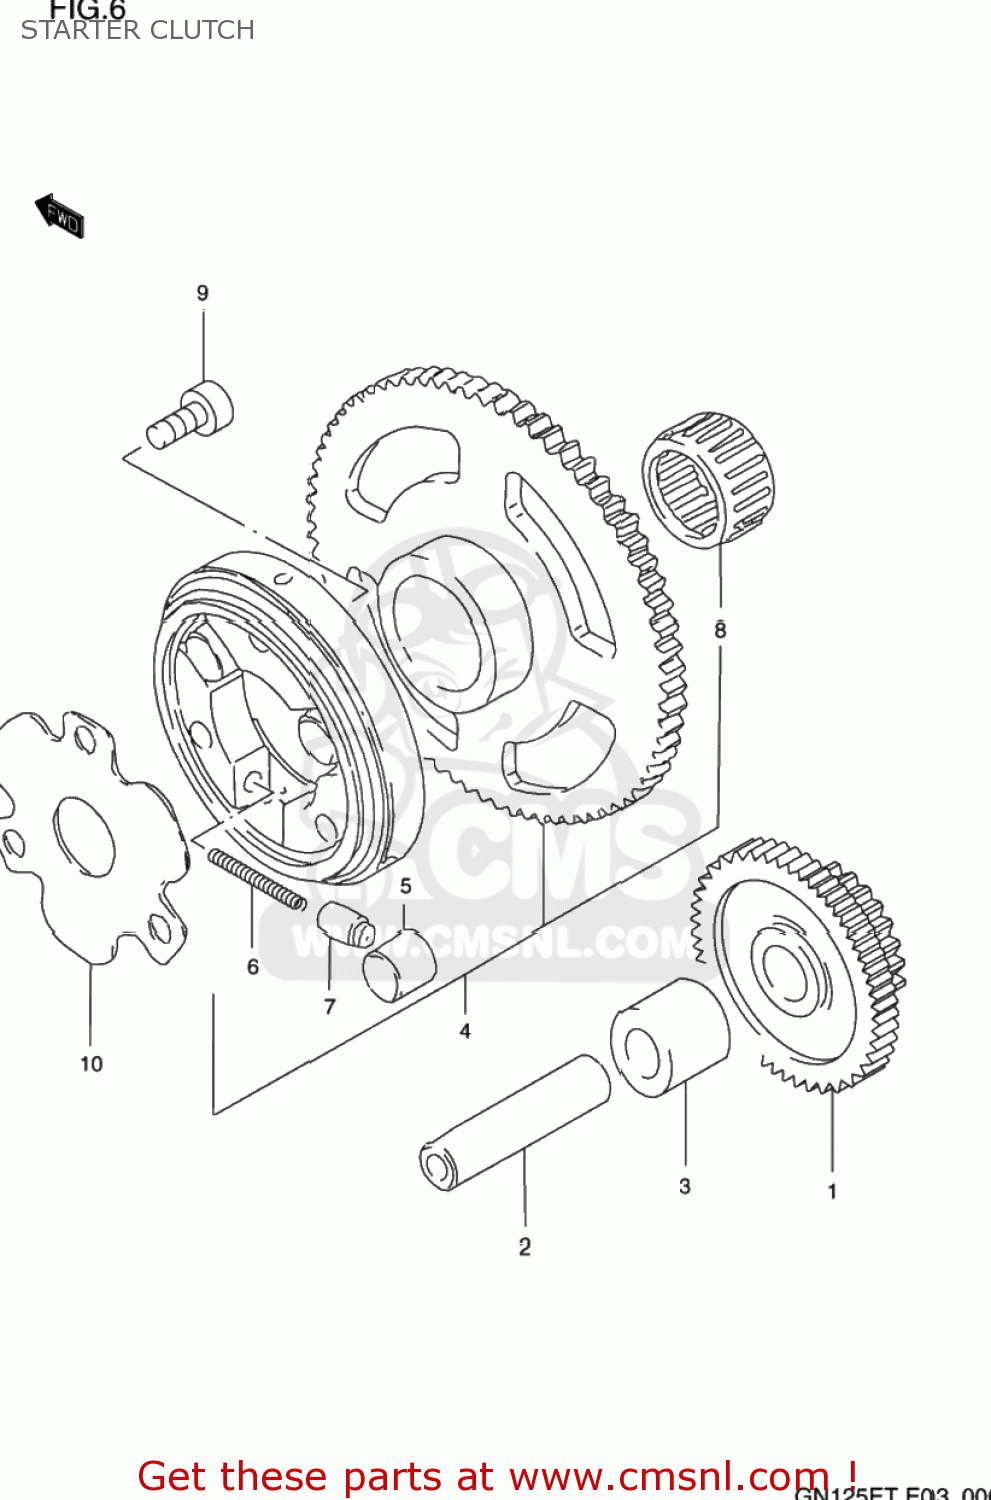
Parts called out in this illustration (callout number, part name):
1	GEAR,STARTER IDLER
2	PIN(7.4X13X56)
3	SPACER(13X19X19)
4	CLUTCH SET,STARTER
5	ROLLER(10X11)
6	SPRING
7	PIECE,STARTER CLUTCH PUSH
8	BEARING(22X28X16)
9	BOLT,OIL FILLE
10	SHIM,STARTER CLUTCH HUB
